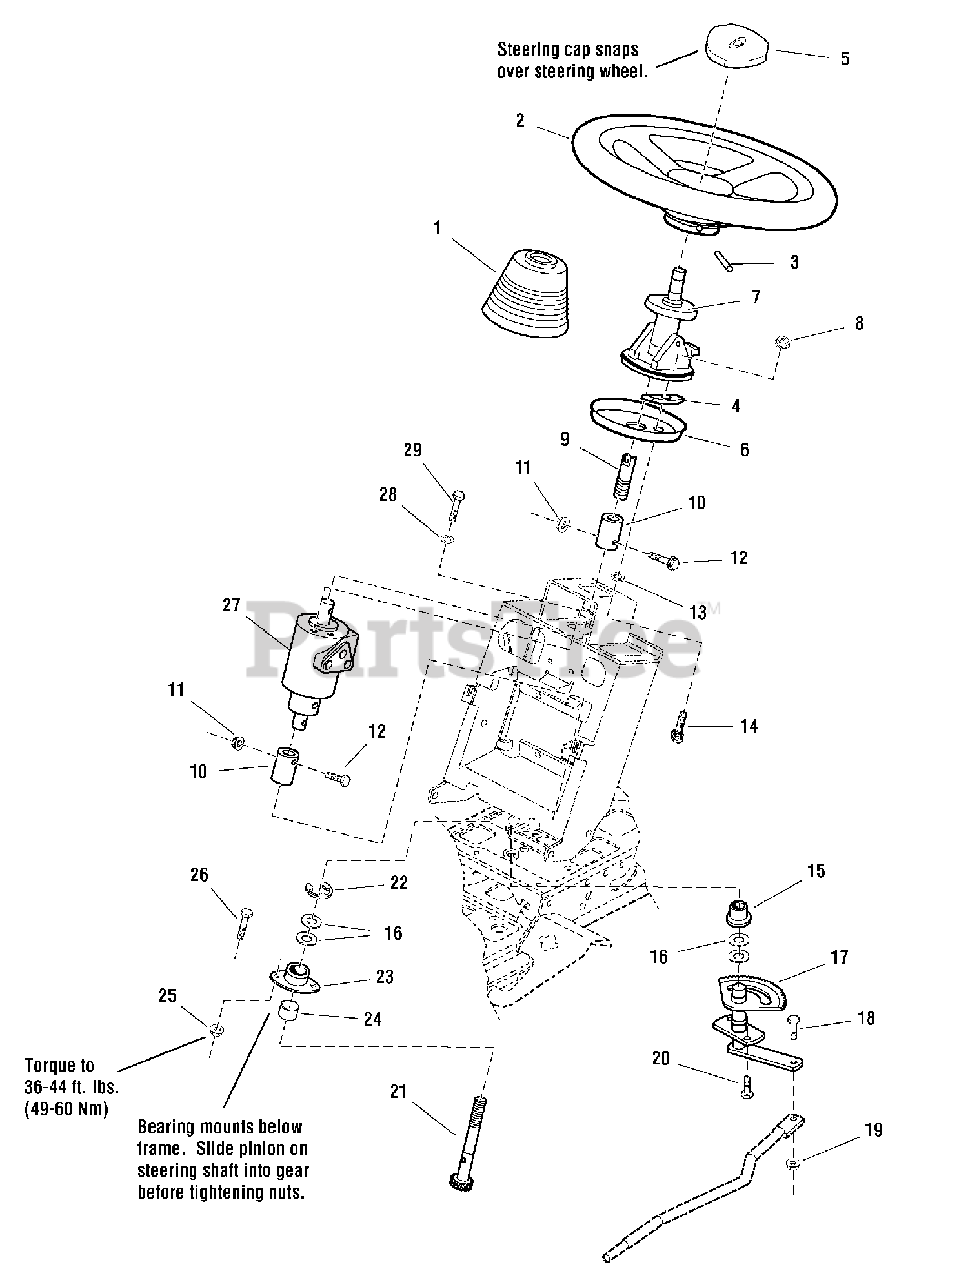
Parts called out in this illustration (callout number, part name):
1	BOOT, Tilt Steering Unit
2	STEERING WHEEL, Straight Shaft
5	CAP, Steering Wheel, Simplicity
5	CAP, Steering Wheel, Plain
6	MOUNTING PLATE
7	TILT STEERING UNIT
8	NUT, Hex KEPS, 5/16-18
9	ADAPTER, Tilt Steering Splined, 2-21/64 Long
10	COUPLER, 2-3/8 Long
11	NUT, Hex Lock, ESNA Light, 5/16-18
12	CAPSCREW, Hex Head 5/16-18 x 1-3/4
13	NUT, Push
14	CARRIAGE BOLT, 5/16-18 x 1
15	BUSHING, Nylon
16	WASHER, 3/4
17	GEAR &, Shaft ASSEMBLY, Steering
18	CAPSCREW, Hex Head, 3/8-16 x 1-1/4
19	NUT, Hex Flange Two-Way Lock, 3/8-16
20	CAPSCREW, Hex Washer Head Taptite, 5/16-18 x 3/4
21	SHAFT & PINION ASSEMBLY, Steering Power wtih Tilt
22	RING, Clipring Extension
23	BEARING, 3/4 x 1-11/16
24	SPACER, 3/8" Long
25	NUT, Hex Flange Whiz Lock, 3/8-16, Small
26	CARRIAGE BOLT, 3/8-16 x 3/4
27	GENERATOR, Torque, Power Steering Unit
28	LOCKWASHER, Spring, 5/16
29	CAPSCREW, Hex Head, 5/16-18 x 3/4
